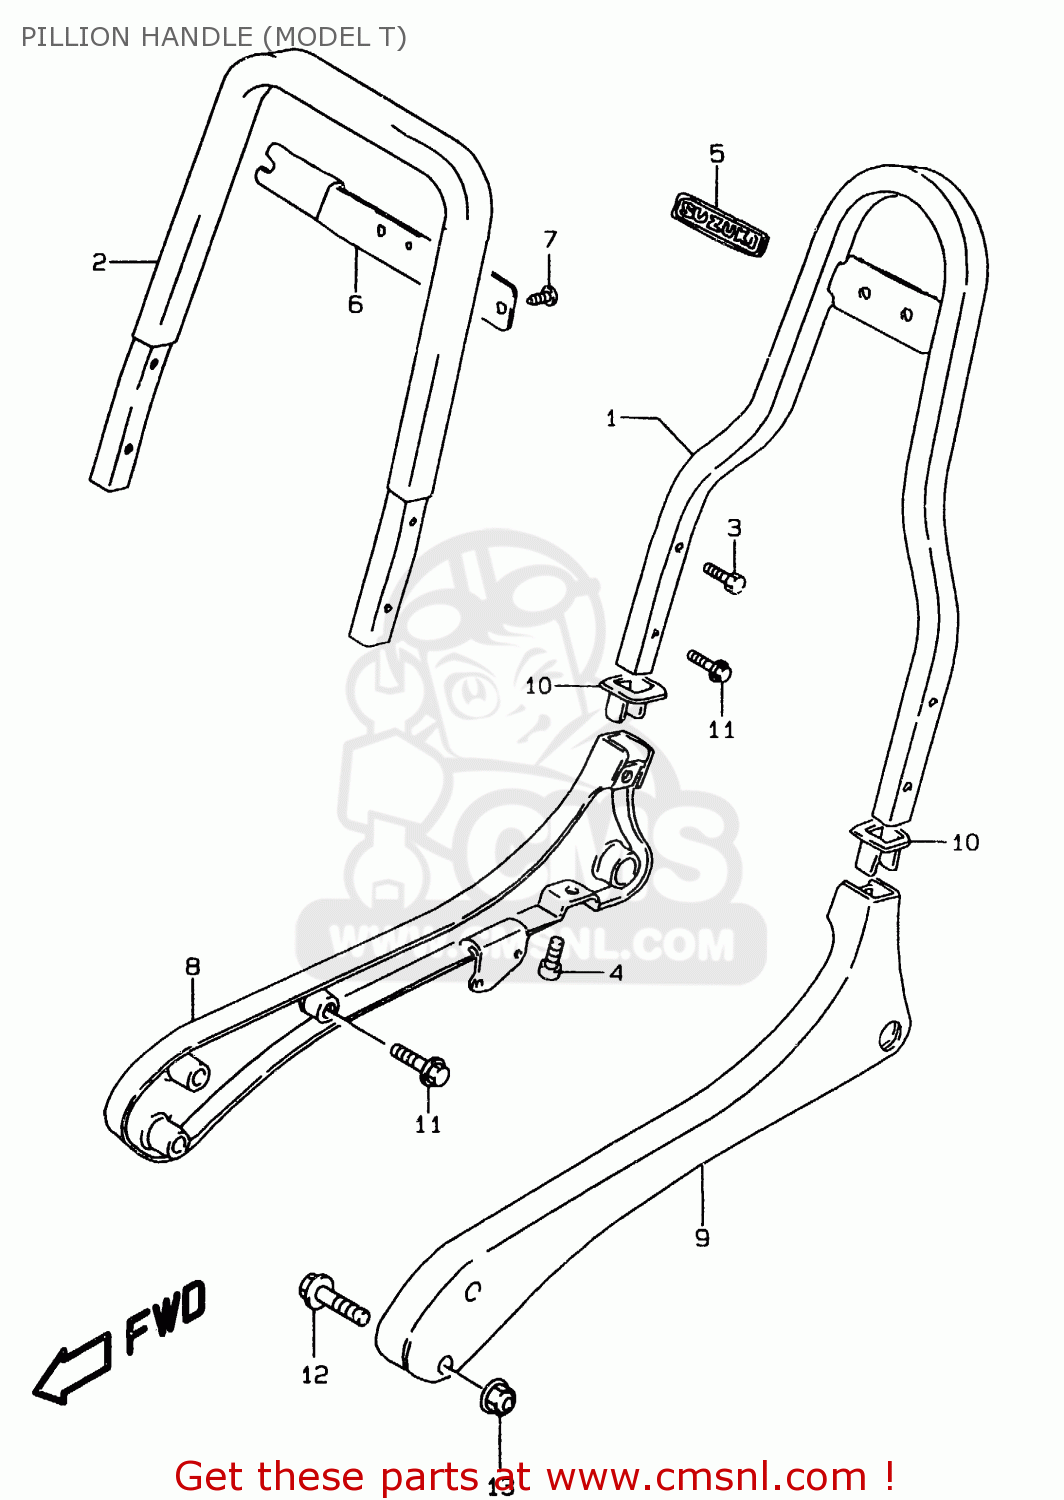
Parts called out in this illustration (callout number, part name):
1	HANDLE,PILLION UPR
2	HANDLE,PILLION RIDER UPPER
3	BOLT
4	PLUG
5	EMBLEM
6	PLATE,RR
7	SCREW 6X10
8	HANDLE,PILLION RIDER,R
9	HANDLE,PILLION RIDER,L
10	COVER,PILLION HNDL
11	BOLT
12	BOLT
13	NUT
